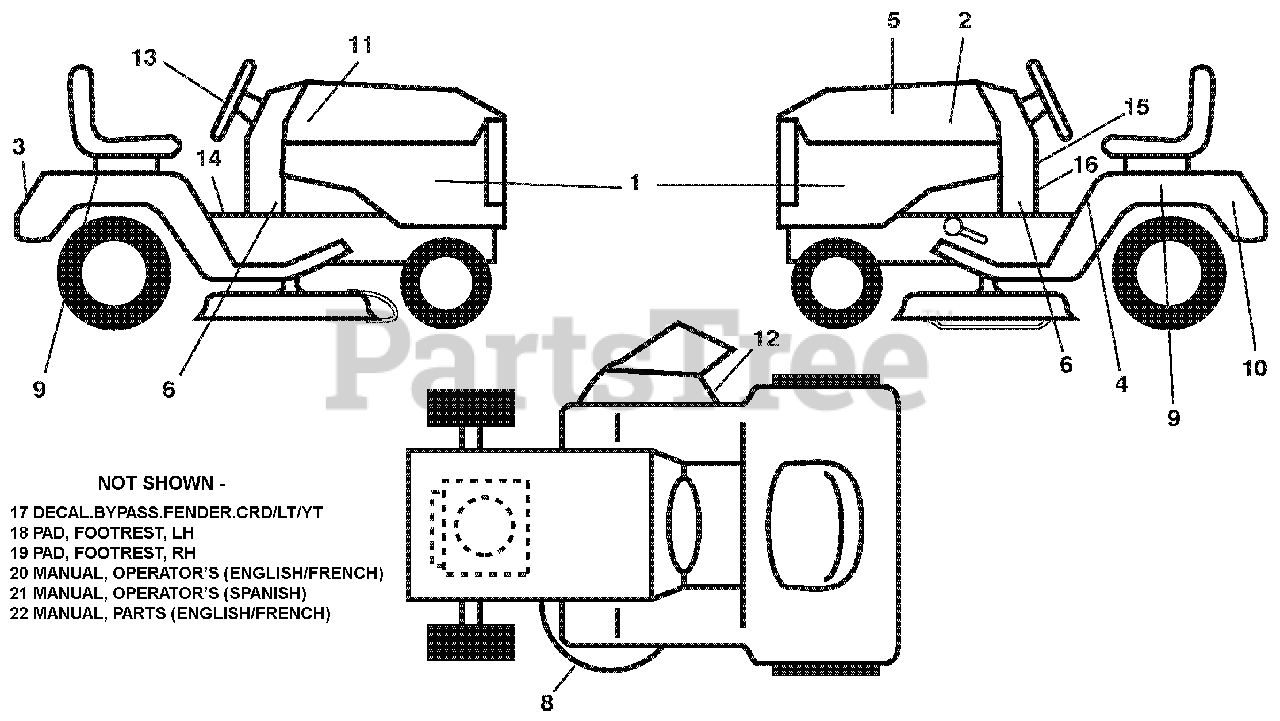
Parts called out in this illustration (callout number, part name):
1	DECAL.SDPNL.PWRDBY KOHL.ARIENS
2	DECAL, HOOD RH
3	DECAL.FENDER.REAR.ARIENS
4	DECAL.FENDER.WARNING.ENG/FR.07
5	DECAL.RPL.KH.SNGL.TLW.42.T2
6	DECAL.DASH.LOWER.19HP.ARIENS
8	DECAL.V-BELT.SCH.42/46"MEC/ELE
9	DECAL.FENDER.SIDE.HYDRO.ARIENS
10	DECAL.BAT.DAN/POI P/L SYM.WPN
11	DECAL, HOOD LH
12	DECAL.MOWER.WARN.KEEP HAND AWY
13	DECAL.WHEEL.STEER.ARIENS
14	Decal, Flag
15	LABEL.COMPLY.EMIS.CA.ARIENS.CP
16	Decal, Spark Arrester
17	DECAL.BYPASS.FENDER.CRD/LT/YT
18	PAD.FOOTREST.LH.TLT.BLACK.428
19	PAD.FOOTREST.RH.TLT.BLACK.428
20	OWNER'S MANUAL, ENGLISH/FRENCH
21	OWNER'S MANUAL SPANISH
22	PARTS MANUAL, ENGLISH/FRENCH
